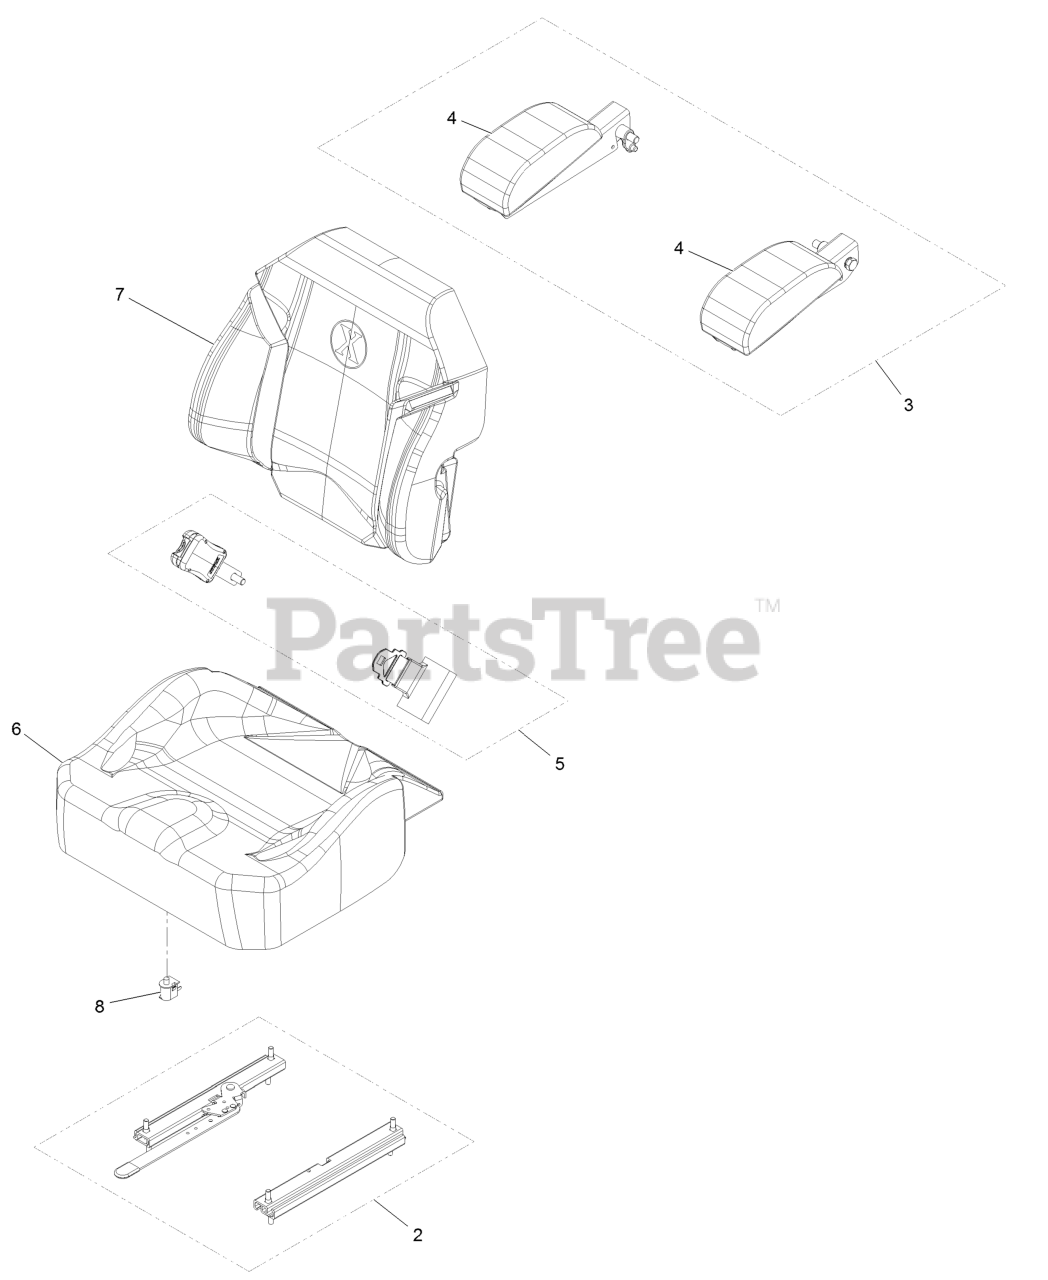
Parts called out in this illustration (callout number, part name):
2	SEAT TRACK SET
3	KIT-ARM REST SET
4	KIT-ARM REST PADS
5	SEAT BELT KIT
6	SEAT CUSHION COVER
7	SEAT BACK COVER
8	SWITCH-BAIL
